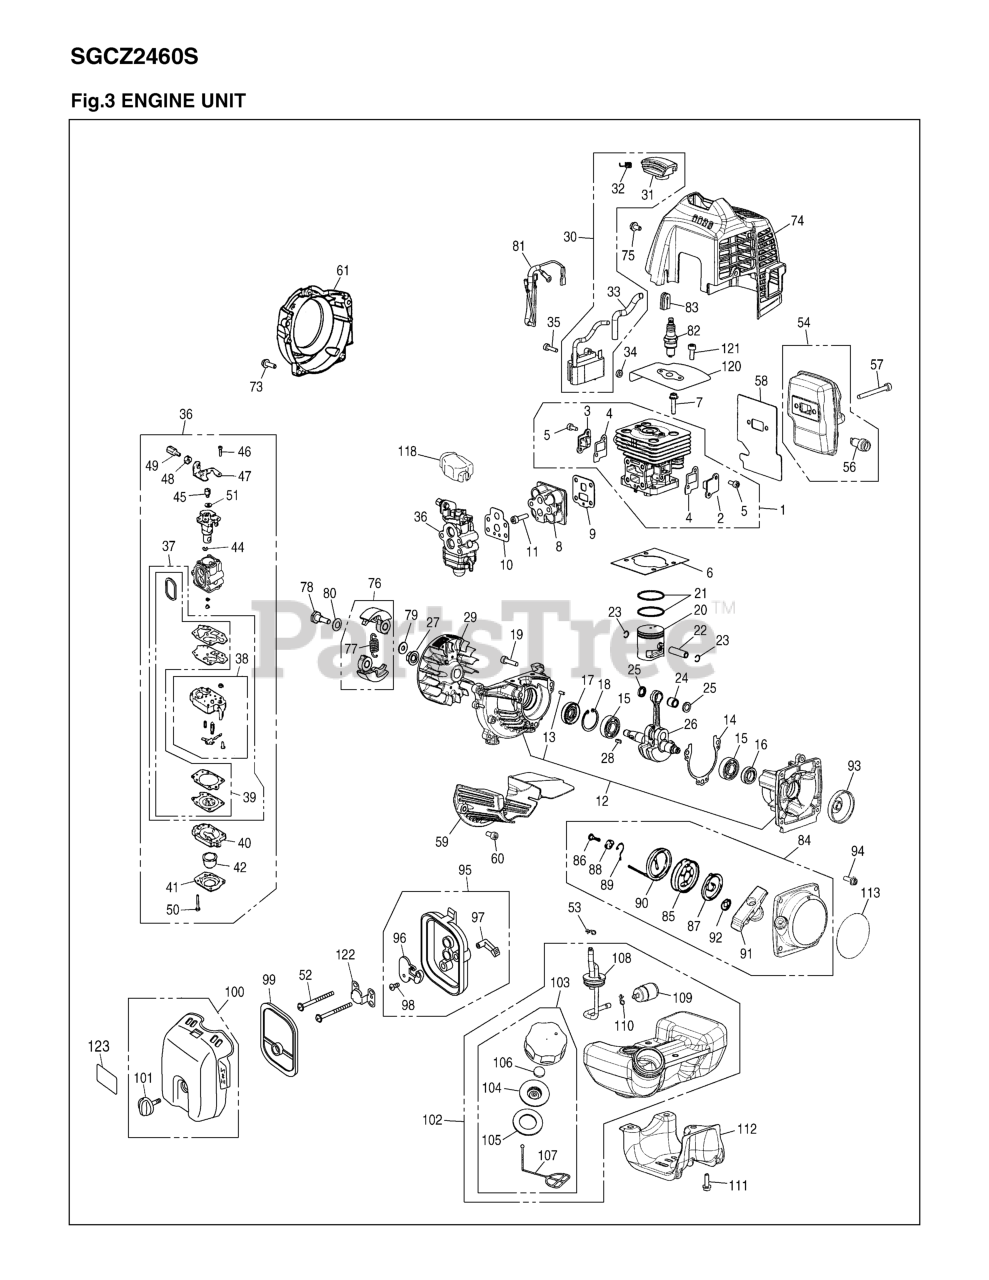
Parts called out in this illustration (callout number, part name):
1	CYLINDER COMP
2	COVER, TR-S
3	COVER, TR-F
4	GASKET, TR
5	BOLT
6	GASKET, BASE
7	BOLT
8	INSULATOR
9	INSULATOR GASKET
10	GASKET, CARB
11	BOLT, TORX
12	CRANKCASE-C
14	GASKET, CASE
15	BEARING MAIN
16	SEAL
17	SEAL, OIL (RPLS
19	BOLT (RPLS 28501
21	RING, PISTON
22	PIN, PISTON
23	RING, SNAP (RPLS
25	WASHER
26	CRANKSHAFT-C
27	NUT (RPLS 1140-4
28	KEY
30	COIL ASSY
31	CAP(RPLS 4810721
35	BOLT TORX
36	CARBURETOR ASSY
37	REBUILD KIT
38	BODY, PUMP
39	GASKET KIT
40	BODY, PURGE
41	COVER, PUMP
42	PUMP, PRIMING
49	SCREW
50	SCREW
51	WASHER
52	BOLT TORX
53	CLIP
56	ARRESTER
57	BOLT
58	GASKET, MUFFLER
60	BOLT
73	BOLT
74	COVER, ENGINE
75	BOLT (RPLS T4950
76	SHOE COMP
77	SPRING
78	BOLT
79	WASHER
80	WASHER (RPLS 114
81	CORD COMP.
82	SPARKPLUG
83	GROMMET
84	RECOIL-A
85	REEL
86	SCREW
87	SPRING, SPIRAL
88	COLLAR
89	ARM
90	ROPE (RPLS 45007
91	KNOB (RPLS 3330-
92	PLATE, STOPPER
93	PULLEY
94	BOLT, TORX
95	CLEANER BODY ASS
96	PLATE, CHOKE
98	SCREW
99	ELEMENT
100	COVER ASSY
101	CLEANER KNOB
102	TANK ASSY
103	CAP ASSY
104	HOLDER (RPLS 450
105	PACKING
106	FILTER
107	STOPPER
108	PIPE-C
109	FILTER
110	CLIP (RPLS 28413
111	BOLT
112	GUARD, TANK
113	LABEL, RECOIL
118	COVER
121	BOLT
